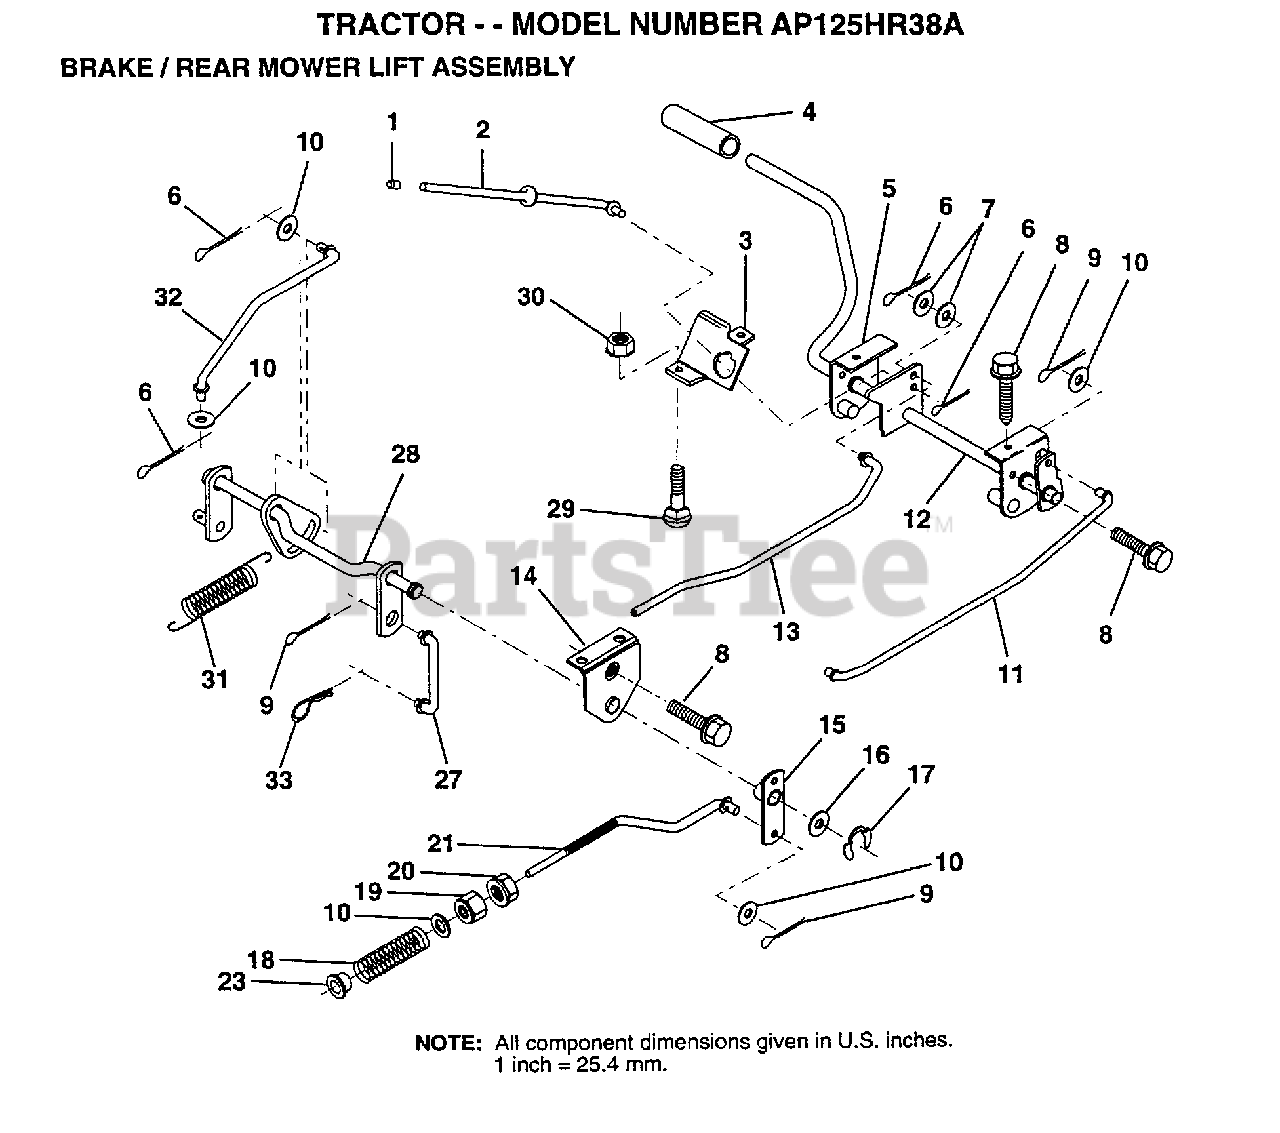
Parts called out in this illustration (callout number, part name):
1	PLUNGER CAP T
2	"ROD,PARK BRAKE"
3	"BRKT,PARK BRAKE"
4	"COVER,PEDAL"
5	BRK ASM CLUT LH
7	WASHER
8	SCREW LT
9	COTTER PIN
10	WASHER
11	"ROD,FRT BRAKE"
12	PEDAL ASM CLU/BRK
13	"ROD,CLUTCH"
14	"BRKT,LIFT SHAFT"
15	PVT BRAKE ARM ASM
16	WASHER T
17	KLIP RING
18	SPRING ROD LT
19	NUT
20	NUT
21	ROD.BRAKE.HYDRO
23	BUSHING.DRAGLINK
27	LINK LIFT REAR LR
28	LIFT.ASM.REAR.LR
31	COUNTER SPRING
32	LINK LIFT LEVER
